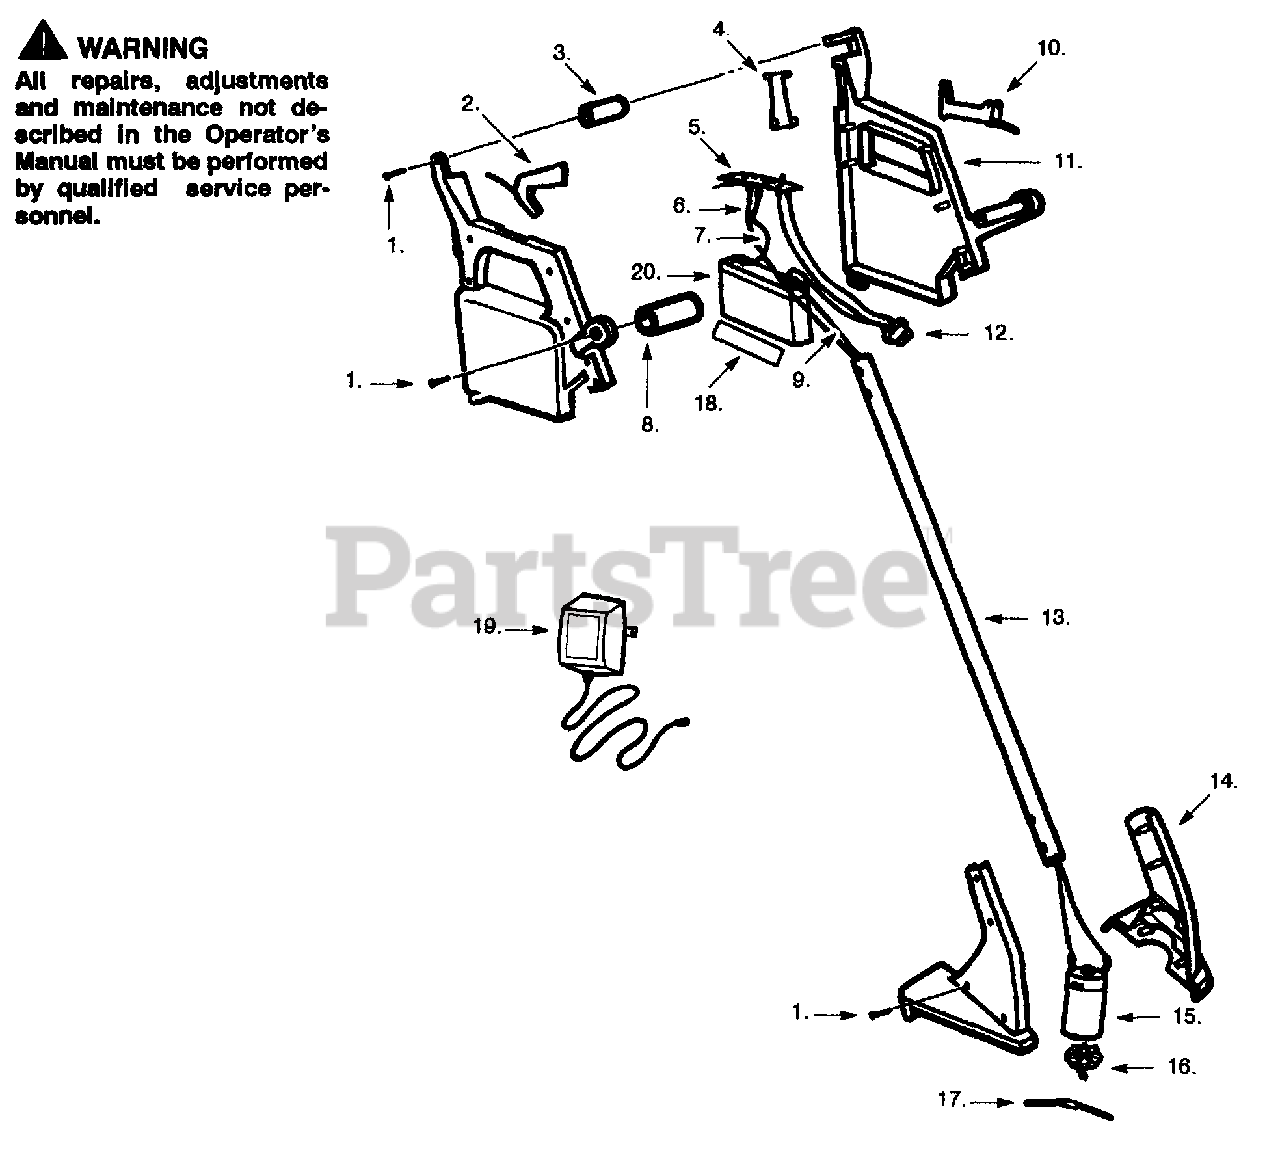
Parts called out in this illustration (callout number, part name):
2	Trigger Lock
3	Wrist Support Cushion
4	Door Line Storage
5	Circuit Board Ass'y.
6	Wire Ass'y. (Red)
7	Wire Ass'y.
8	Assist Handle Cushion
9	Wire Ass'y. (Black)
10	Trigger Switch
11	Battery Hsg. Set
12	Recepticle Ass'y.
13	Tube w/ Warning Decal
14	Motor Hsg. Set
16	Hub w/Line Retainer
18	Foam Spacer
20	Battery
